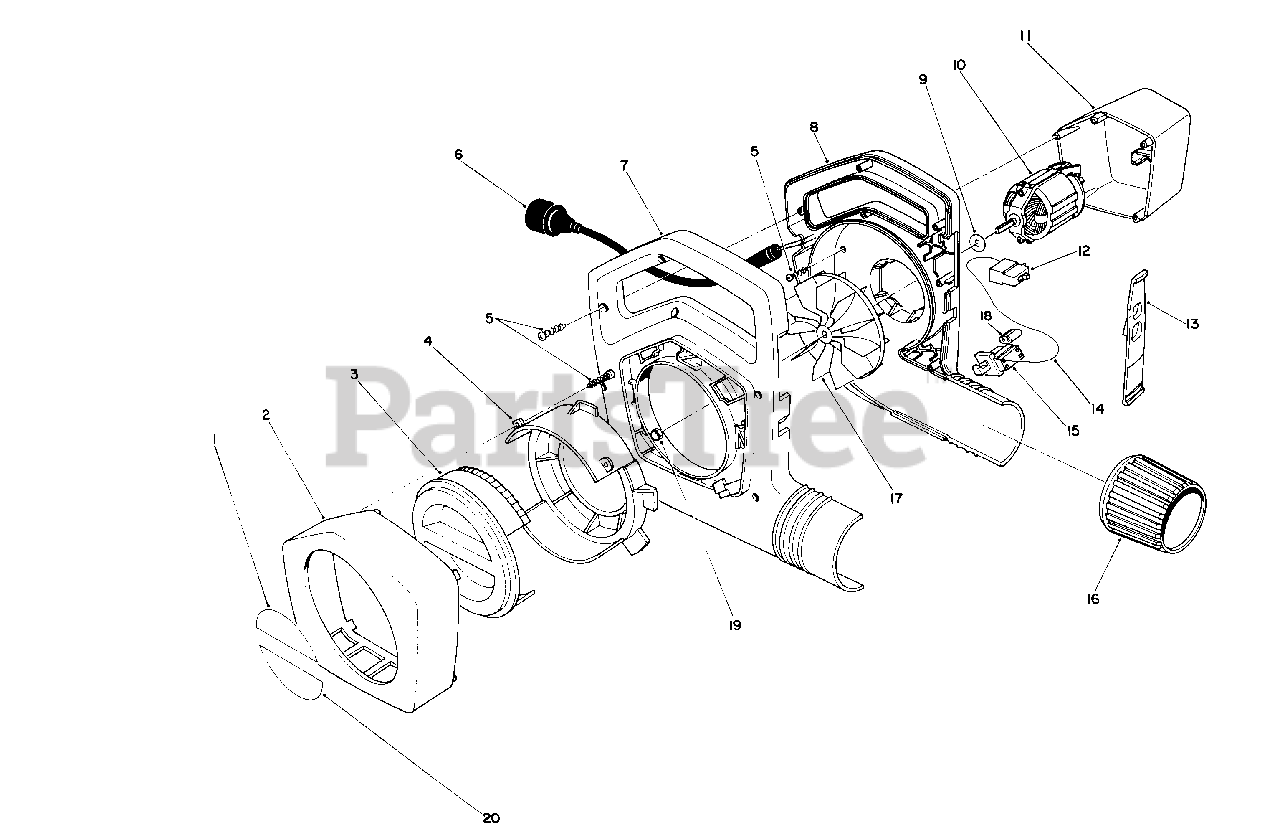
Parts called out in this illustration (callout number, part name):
1	Decal-Upper Choke
2	Ring-Trim
3	Adjuster-Choke
4	Ring-Tab
5	Screw
6	Cord-Power Supply
7	Housing Assembly-R.H.
8	Housing-L.H.
9	Washer-Impeller (used on units with serial no. 9000001 thru 9000469)
9	Washer-Impeller(used on units with serial no. 900470 & up)
10	Motor (used on units with serial no. 9000001 thru 9000469)
10	Motor (used on units with serial no. 900470 & up)
11	Cover-Motor (used on units with serial no. 9000001 thru 9000469)
11	Cover-Motor (used on units with serial no. 9000470 & up)
12	Switch-On/Off
13	Cam-Switch-On/Off
14	Wire-Internal
15	Switch-Interlock
16	Collar-Output
17	Impeller (used on units with serial no. 9000001 thru 9000469)
17	Impeller (used on units with serial no. 9000470 & up)
18	Plug-Dust
19	Nut-Cap Decal-Lower
